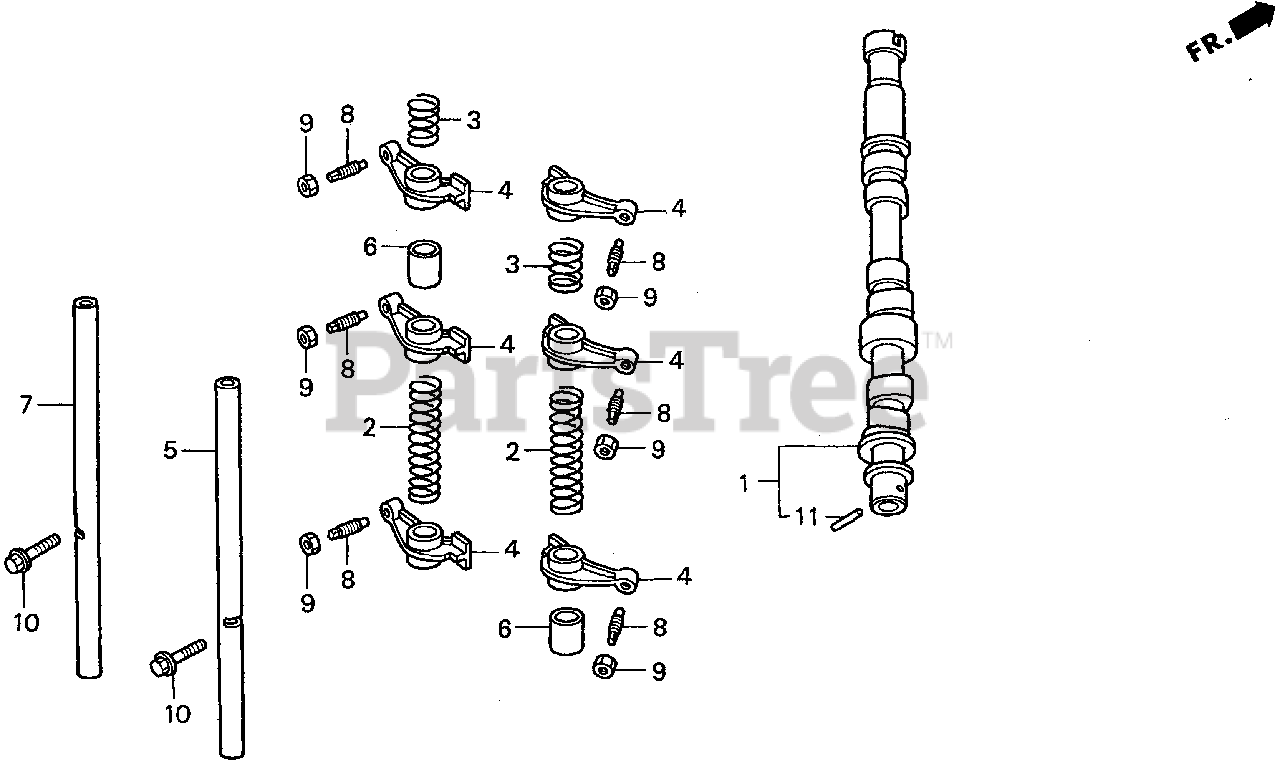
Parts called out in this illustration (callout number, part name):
2	SPRING, ROCKER ARM A
3	SPRING, ROCKER ARM B
4	ARM, VALVE ROCKER
5	SHAFT, IN. ROCKER
6	COLLAR, ROCKER
7	SHAFT, EX. ROCKER
8	SCREW, TAPPET ADJ.
9	NUT, TAPPET ADJ.
10	BOLT, FLANGE (6X28)
11	ROLLER (3X16.8)
